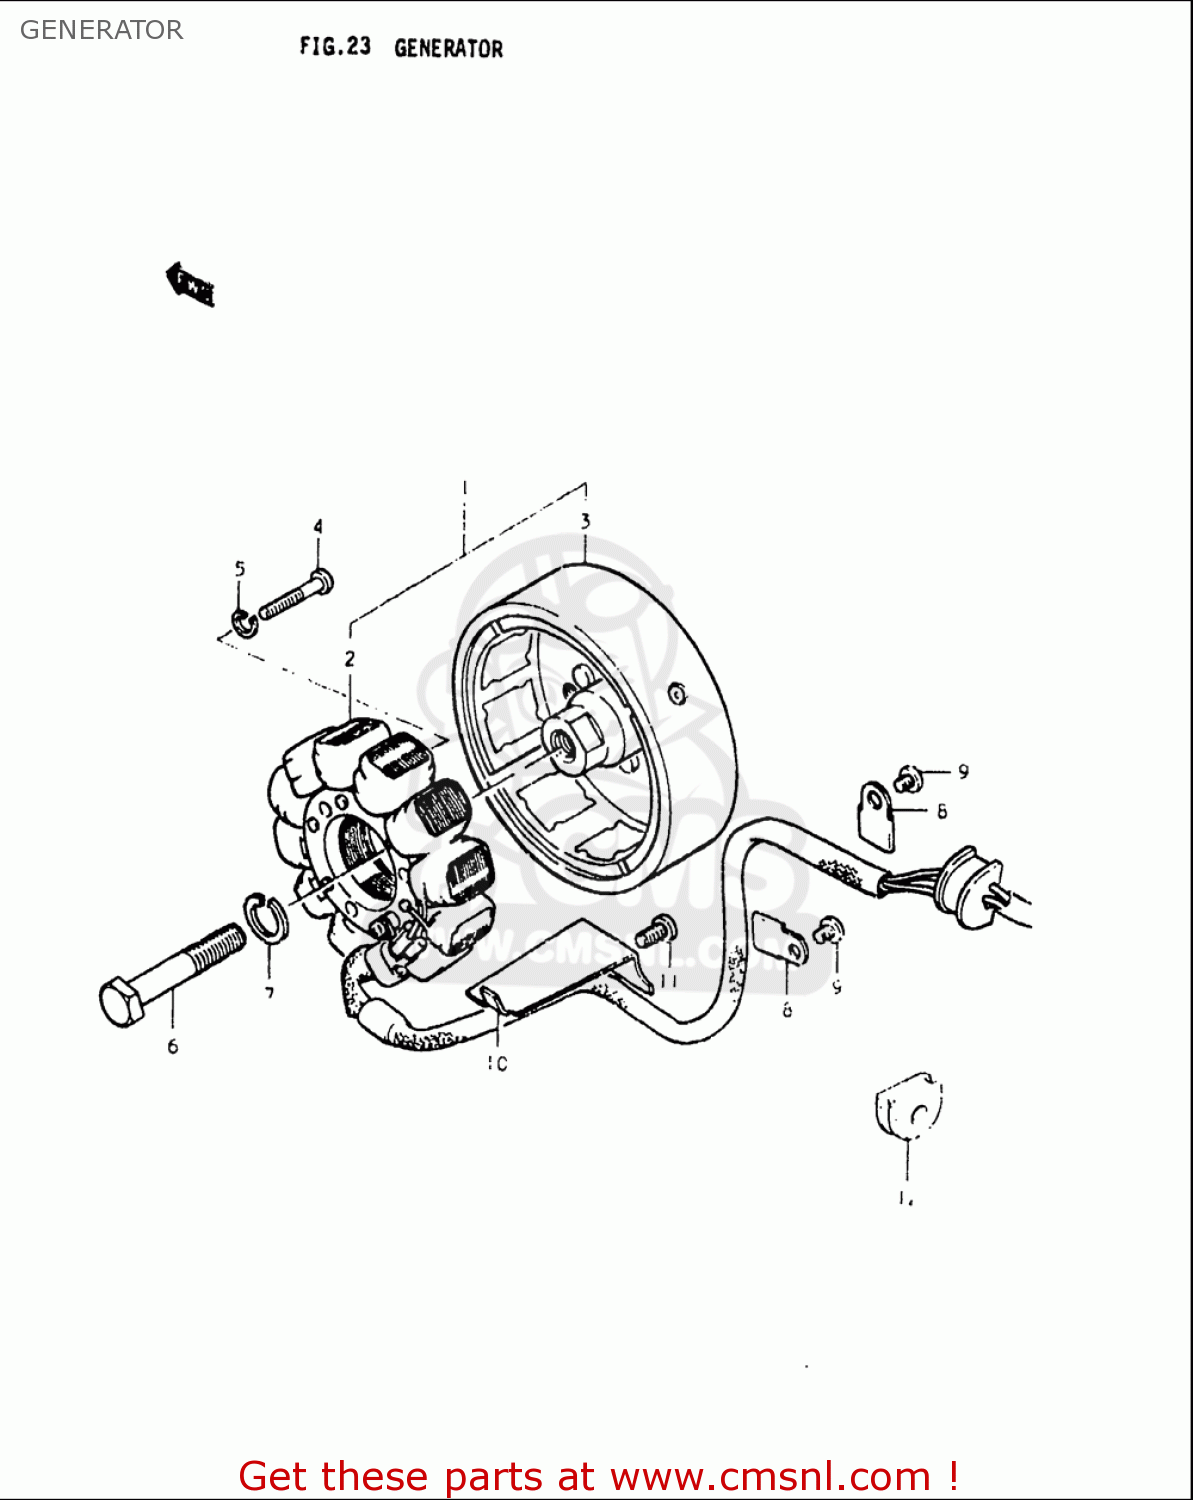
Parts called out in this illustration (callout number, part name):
1	STARTER ASSY
2	STARTER ASSY
3	ROTOR ASSY
4	SCREW
5	WASHER,LOCK
6	BOLT
7	WASHER,LOCK
8	CLAMP,GENERATOR LEAD WIRE
9	SCREW(5X6)
10	CLAMP,GENERATOR LEAD WIRE
11	SCREW
12	GROMMET,STARTER CABLE
